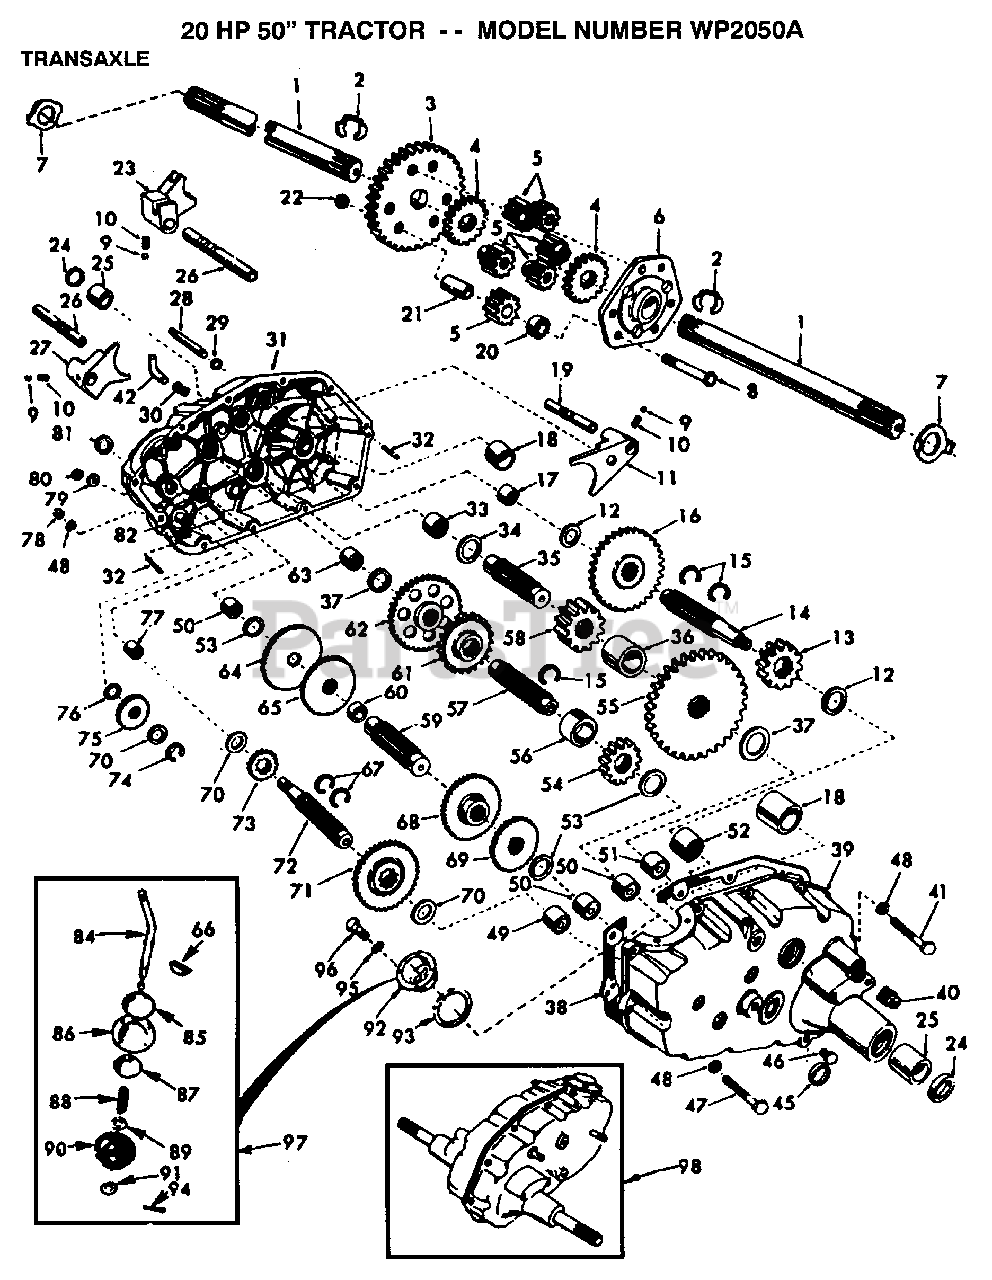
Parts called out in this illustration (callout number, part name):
1	SHAFT.AXLE.T
2	KLIP RING
3	FINAL GEAR T
4	DIFF GEAR T
5	DIFF PINION T
6	DIFF CARRIER T
8	BOLT
11	SHIFT FORK T
12	WASHER .T
13	RED PINION T
14	GEAR SHAFT T
15	SNAP RING T
16	GEAR T
17	"T, BEARING"
18	BEARING
19	SHAFT
20	SPACER T
21	PINION RS
22	GRIPCO NUT
23	FORK T
24	OIL SEAL STD
25	BRNG. T
27	SHIFT FORK T
28	SHIFT SHAFT
29	SEAL T
30	VALVE M
31	GEARCASE RH
32	PIN T
33	NEEDLE BRNG T
34	RACE T
35	GEAR SHAFT T
37	RACE T
38	GASKET
39	GEARCASE LH
40	PLUG PIPE
41	BOLT
42	ELBOW STREET 90
45	SEAL T
47	HEX BOLT
49	"TI, BEARING"
50	NEEDLE BRNG T
51	NEEDLE BRNG T
52	"STD, BEARING"
53	BRNG RACE
54	RED PINION T
55	RED GEAR T
56	PINION SPACER T
57	GEAR SHAFT T
58	FINAL PINION T
59	GEAR SHAFT T
60	SPACER T
61	RED PINION T
62	RED GEAR T
63	RACE T
64	LOW SPEED GEA T
65	REVERSE GEAR T
66	KEY T
67	RING STD
68	INTERMED GEAR T
70	"T, BEARING"
71	CLUSTER GEAR T
72	INPUT SHAFT T
73	LO SPEED PINION T
75	IDLER GEAR T
76	WASHER T
77	BRNG T
78	NUT.HEX.5/16-18
79	WASHER T
80	NUT
81	SEAL STD
84	GEAR SHIFT LVR T
85	CAP T
86	COVER AND PIN T
87	GUIDE BALL T
88	SPRING TI
89	WASHER
90	SEAL T
91	WASHER
92	GEAR SHIFT GA T
93	GASKET T
94	COTTER PIN
95	LOCKWASHER
96	BOLT
97	GEAR SHFT LVR T
